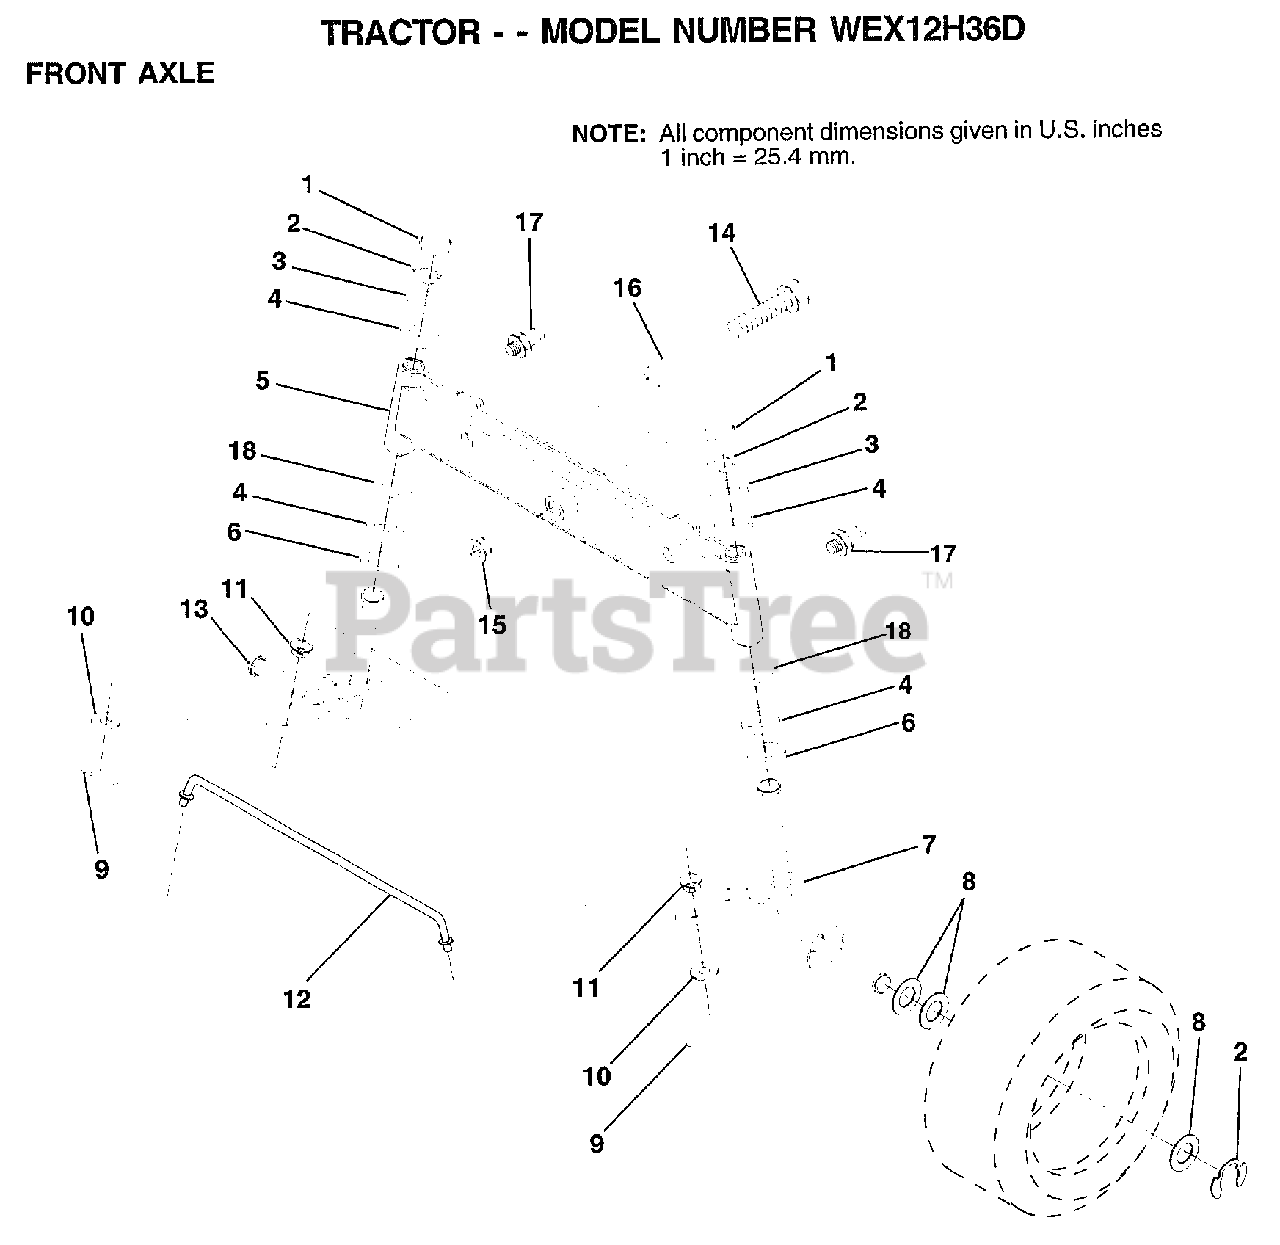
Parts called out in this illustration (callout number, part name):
1	CAP
2	RING
3	WASHER
4	COL. SRTG. BEAR.
5	AXLE ASM FRONT
6	WASHER .T
7	SPINDLE.ASSY.RH
8	WASHER
9	COTTER PIN
10	WASHER
11	BUSHING.DRAGLINK
12	TIE ROD
13	SPINDLE.ASSY.LH
14	BOLT HEX 5/8-11
15	"NUT-LOC,FLANGE LT"
16	BEARING
17	ZERK M
18	WASHER
